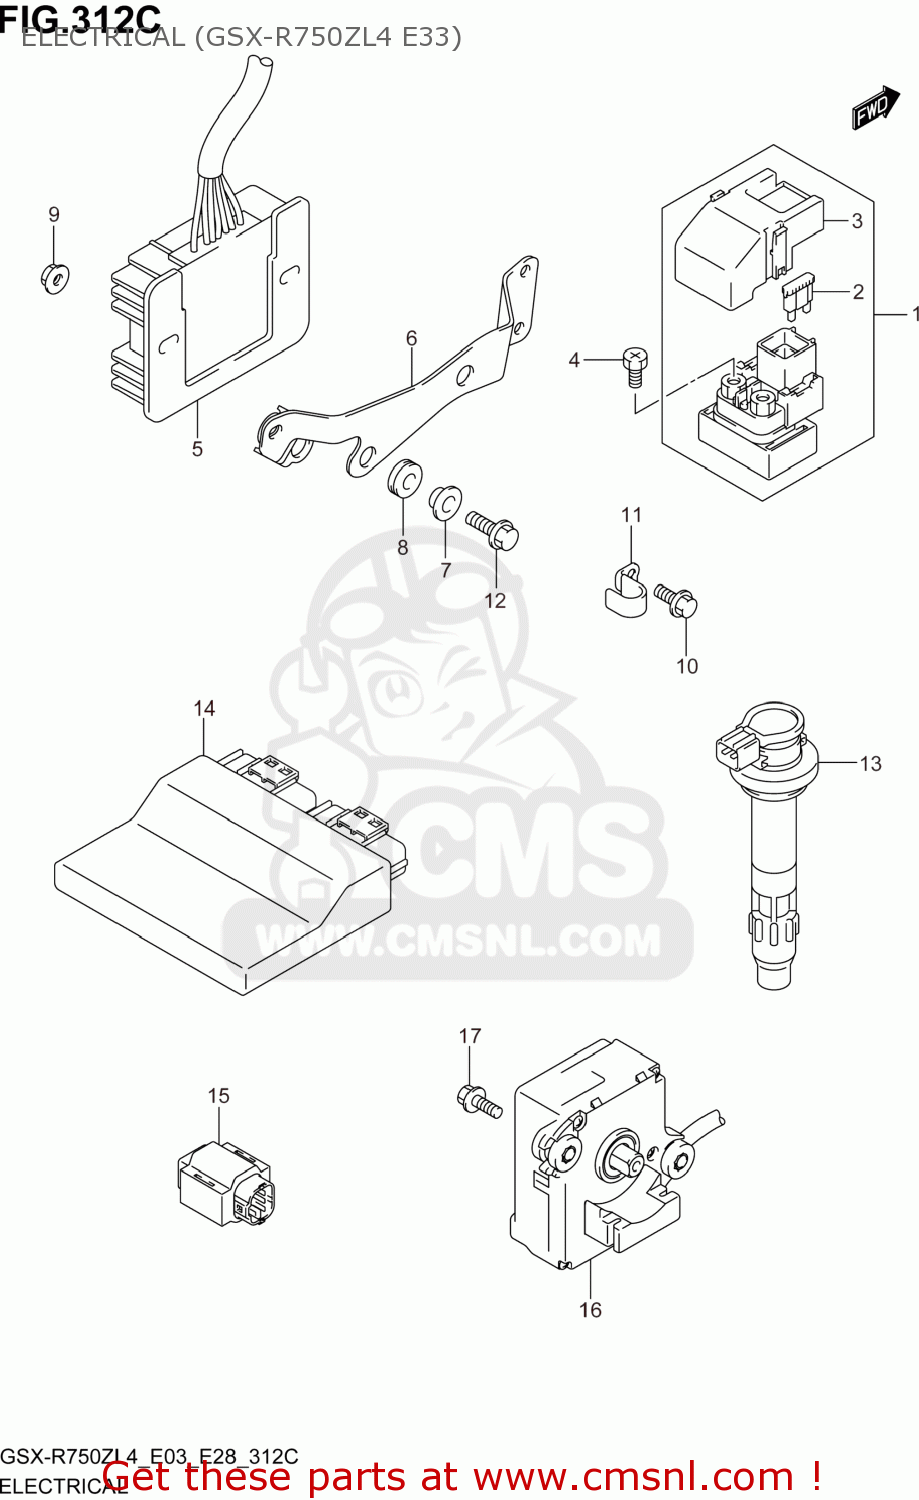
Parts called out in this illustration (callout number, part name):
1	RELAY ASSY,STARTING MOTOR
2	FUSE(30A)
3	COVER
4	SCREW(6X8)
5	RECTIFIER ASSY
6	BRACKET,RECTIFIER
7	SPACER(6.2X8.4X6.9)
8	CUSHION
9	BOLT(6X20)
10	BOLT
11	CLAMP(L:80)
12	NUT
13	COIL ASSY,IGNITION
14	CONTROL UNIT,FI
15	SENSOR ASSY,FUEL CUT
16	ACTUATOR ASSY,EXHAUST CONTROL
17	BOLT(6X32.5)
